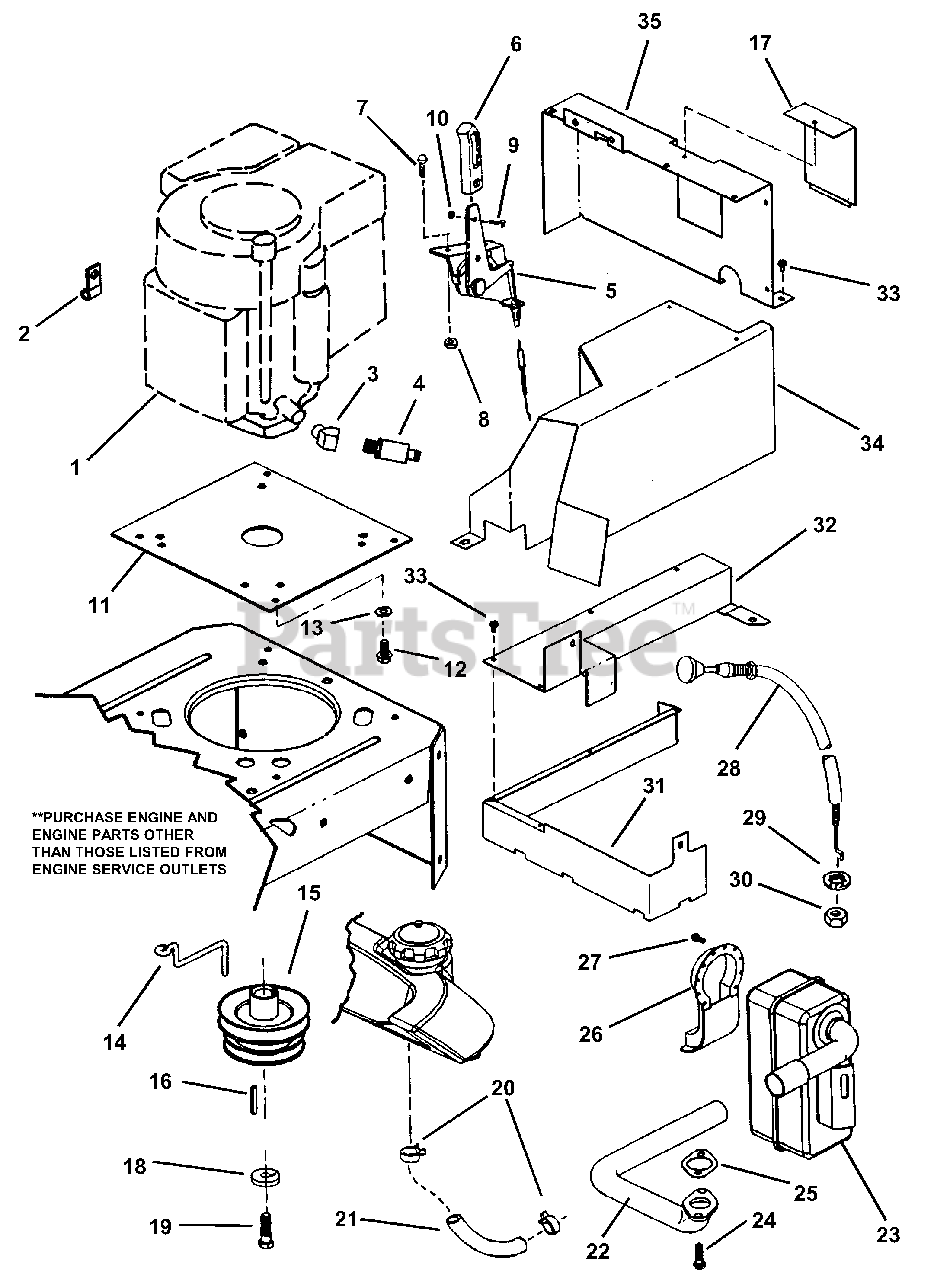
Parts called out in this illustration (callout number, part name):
1	ENGINE, 18 HP Briggs (Model 350777, Type 1142, Trim E1)
1	ENGINE, 14 HP Briggs OHVIC (B&S 2877Q7-0122-01)
1	ENGINE, 15 HP Kohler (Model CV15S, Type PS41570)
2	WIRE CLIP, 7/16"
3	FITTING, Oil Drain 90
4	ASSEMBLY, Oil Valve
5	CONTROL, Throttle
6	LEVER, Throttle Control
7	SCREW, #10-32 x 5/8" Hex Washer Head, Grade 5
8	NUT, #10-32 Nyloc
9	SCREW, #8-32 x 3/8" Machine
10	NUT, #8-32 Hex
11	PLATE, Engine
12	SCREW, 3/8-16 x 1" Hex Washer Head (Briggs)
12	SCREW, M8-1.25 x 25mm Hex Washer Self-Tapping (Kohler)
13	WASHER, 5/16 Split Lock (Kohler)
14	GUIDE, Belt
15	PULLEY, Engine
16	KEY, 1/4" Square x 2"
17	COVER, Spark Plug Access (Briggs 14HP)
18	WASHER, 7/16" Split Lock
19	SCREW, 7/16-20 x 1-1/2" Hex Head Cap, Grade 5
20	CLAMP, Fuel Hose
21	HOSE, Fuel 1/4" I.D. x 20" (Briggs 14 HP)
21	HOSE, Fuel 1/4" I.D. x 14" (Kohler 15 HP)
22	PIPE, Exhaust (Briggs 14HP)
22	PIPE, Exhaust (Kohler 15HP)
22	PIPE, Exhaust (Briggs 18HP)
23	MUFFLER
24	SCREW, 5/16-18 x 3/4" Hex Head Cap, Grade 5 (Briggs 14HP)
25	GASKET, Exhaust (Briggs 14HP)
26	DEFLECTOR, Muffler (42" Deck only)
27	SCREW, #8-18 x 1/2" (42" Deck only)
28	CONTROL CABLE, Choke (Kohler 15HP)
29	WASHER, 3/8" Internal Tooth Lock (Kohler)
30	NUT, 3/8-24 Hex (Kohler 15HP)
31	HEAT SHIELD, Sides (Kohler 15HP)
32	HEAT SHIELD, Top (Kohler 15HP)
33	SCREW, #10-32 x 3/8" Sheet Metal
34	DUCT, Right Hand (Briggs 14HP)
35	DUCT, Front (Briggs 14HP)
